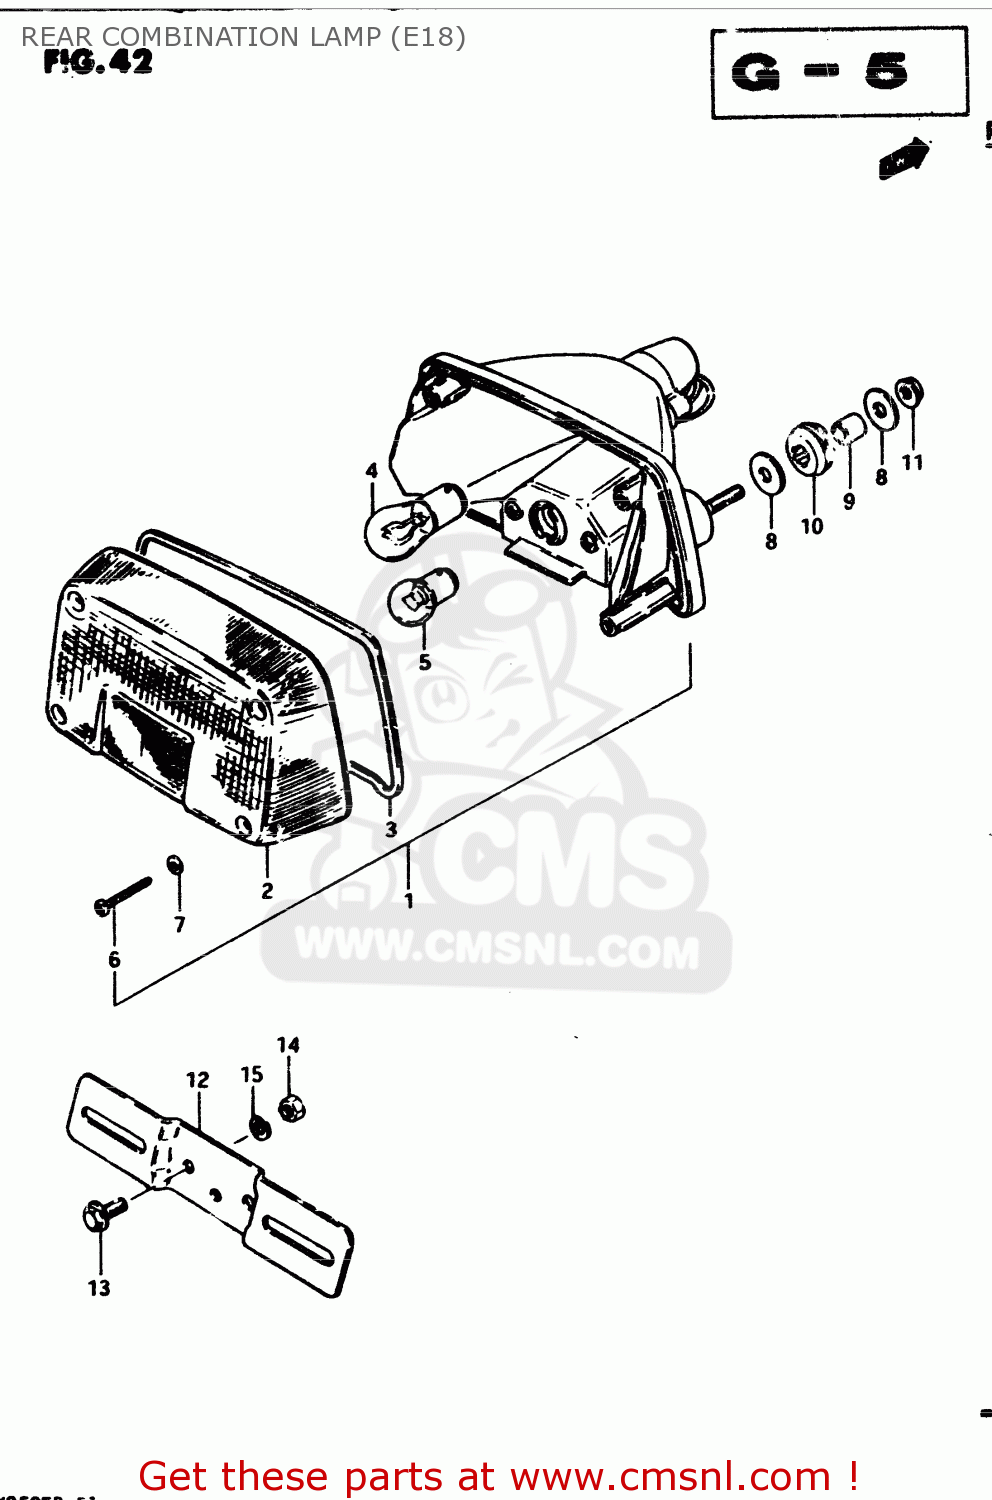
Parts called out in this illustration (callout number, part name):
1	LAMP ASSY, REAR COMBINATION
2	LENS,RR COMBI
3	GASKET
4	BULB(12V21/5W)
5	BULB
6	SCREW
7	GASKET (NAS)
8	WASHER
9	SPACER (6.8X10X11.5)
10	CUSHION
11	NUT 6MM
12	BRACKET, LICENSE PLATE
13	BOLT
14	NUT
15	LOCK WASHER
